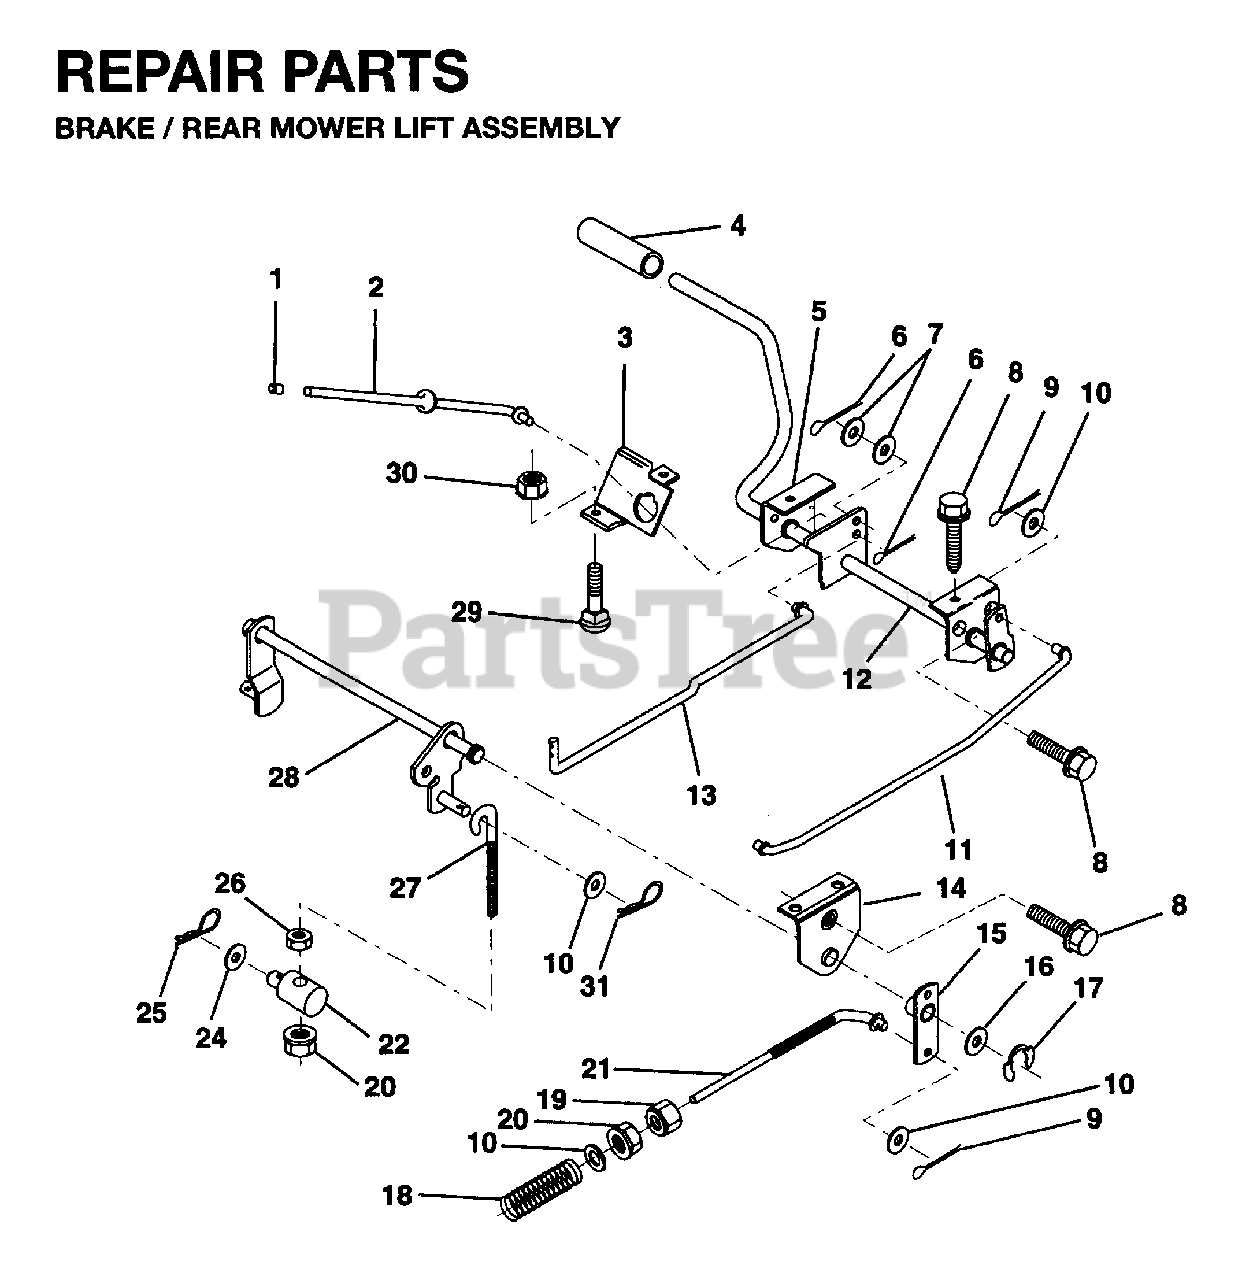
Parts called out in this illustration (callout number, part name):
1	PLUNGER CAP
2	ROD,PARK BRAKE
3	BRKT,PARK BRAKE
4	PEDAL COVER T
5	BRKT,CLU PEDAL LH
6	COTTER PIN
9	COTTER PIN
10	WASHER
11	ROD,FRT BRAKE
12	CLUTCH/BRAKE PEDAL ASSY
13	ROD,CLUTCH
14	BRKT,LIFT SHAFT
15	ARM, BRAKE ASMBLY
17	KLIP RING
18	SPRING ROD LT
19	NUT.HEX.3/8-16UNC
20	LOCKNUT
21	ROD REAR BRAKE
22	TRUNNION, LEFT
25	SPRING.RETAINER
26	LOCKNUT
27	LINK.MOWER.REAR
28	REAR MOWER LIFT ASSY
30	LOCKNUT
31	SPRING RETAINER
